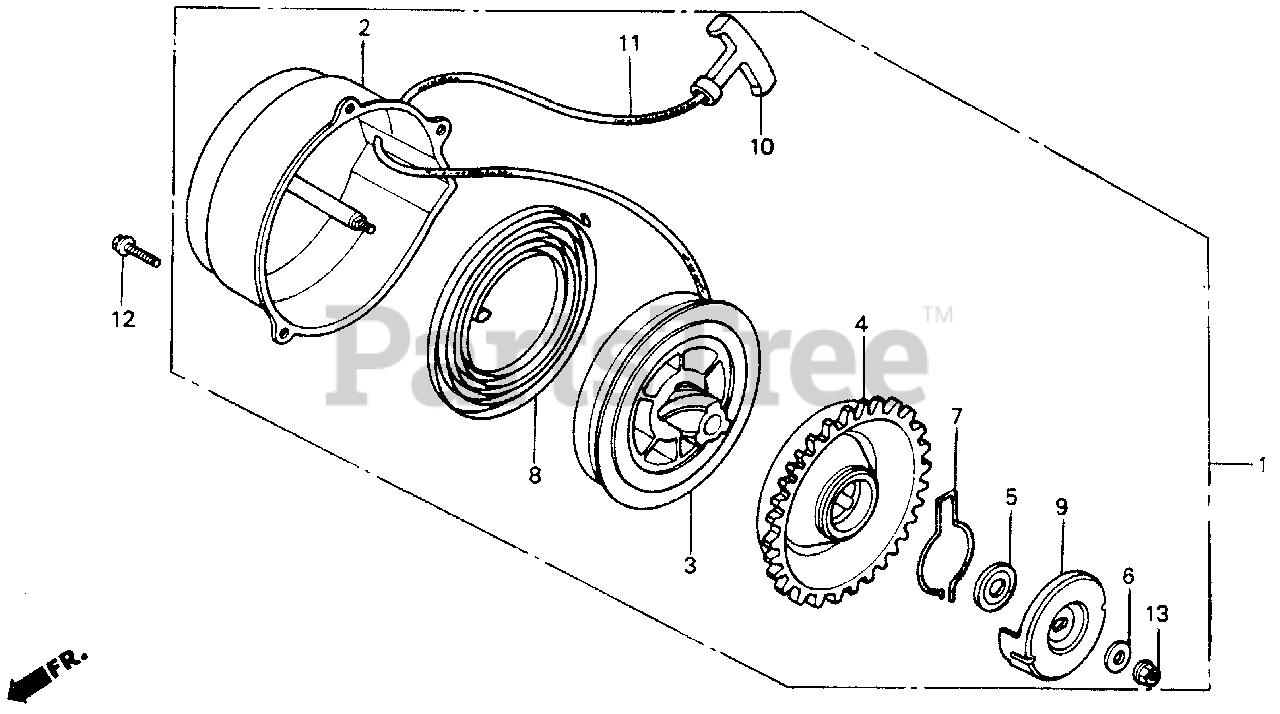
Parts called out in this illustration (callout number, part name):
1	STARTER ASSY., RECOIL (NOT AVAILABLE)
2	CASE, RECOIL STARTER (NOT AVAILABLE)
3	PULLEY, STARTER (NOT AVAILABLE)
4	GEAR, STARTER (NOT AVAILABLE)
5	WASHER, THRUST
7	SPRING, FRICTION
8	SPRING, STARTER RETURN (NOT AVAILABLE)
9	RETAINER, SPRING
10	GRIP, STARTER (NOT AVAILABLE)
11	ROPE, RECOIL STARTER (#4X91")
12	BOLT, FLANGE (6X12) (CT200)
13	NUT, FLANGE (6MM)
